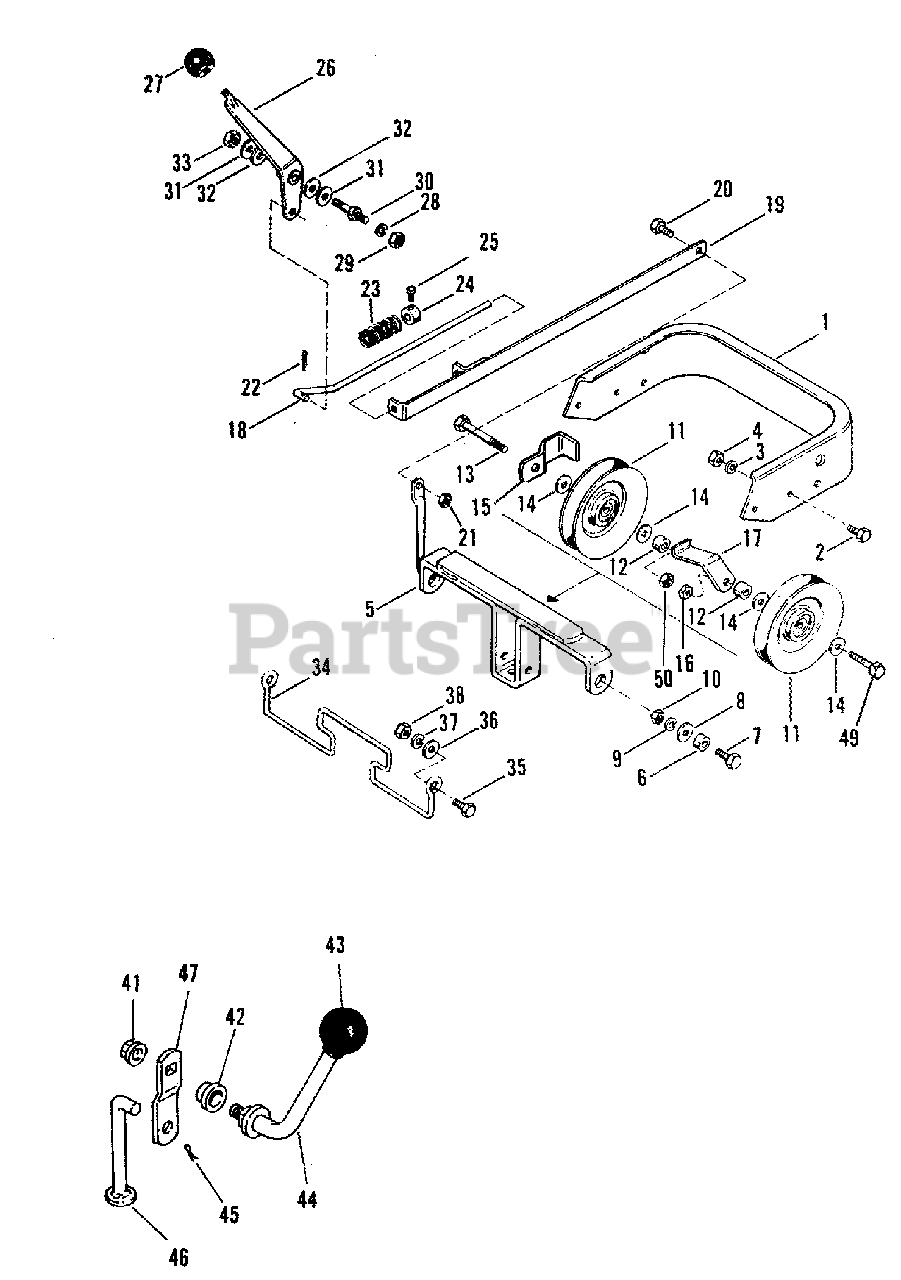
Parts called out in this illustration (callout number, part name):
1	BUMPER, Front
2	CAPSCREW, Hex 5/16-18 x 3/4" Large
3	LOCKWASHER, 5/16"
4	NUT, Hex, Full 5/16"-18
5	CLEVIS ASSEMBLY, Pulley
7	CAPSCREW, Hex, 3/8"-16 x 1" Large
8	WASHER, Plain, 3/8"
9	LOCKWASHER, 3/8"
10	NUT, Hex, Full, 3/8-16"
13	CAPSCREW, 3/8-24 x 1-3/4" Large
14	WASHER, Plain, 3/8"
15	STOP, Belt
16	LOCKNUT, Full Hex, 3/8"-16
18	ROD, Clutch, P.T.O.
19	GUIDE ASSEMBLY, Idler
20	CAPSCREW, Hex, 3/8"-16 x 3/4" Large
21	LOCKNUT, Full Hex, 3/8"-16
22	PIN, Cotter, 3/32 x 5/8" Large
24	COLLAR, Set
25	SCREW, Set, 1/4-20 x 3/8" Large
26	LEVER ASSEMBLY
28	LOCKWASHER, 5/16"
29	NUT, Hex, Full, 5/16-18"
31	WASHER, Plain, 5/16"
32	WASHER, Special
33	NUT, Hex, Full Lock, 5/16-18"
34	stop, Belt, P.T.O.
35	CAPSCREW, Hex, 5/16"-18 x 3/4" Large
36	WASHER, Plain, 5/16"
37	LOCKWASHER, 5/16"
38	NUT, Full Hex, 5/16-18"
39	CAPSCREW, Hex, 3/8-24 x 2" Large
40	LOCKNUT, Full Hex, 3/8"-24
41	LOCKNUT, 3/8"
44	HANDLE, Clutch
45	PIN, Cotter
47	ARM, Lift
